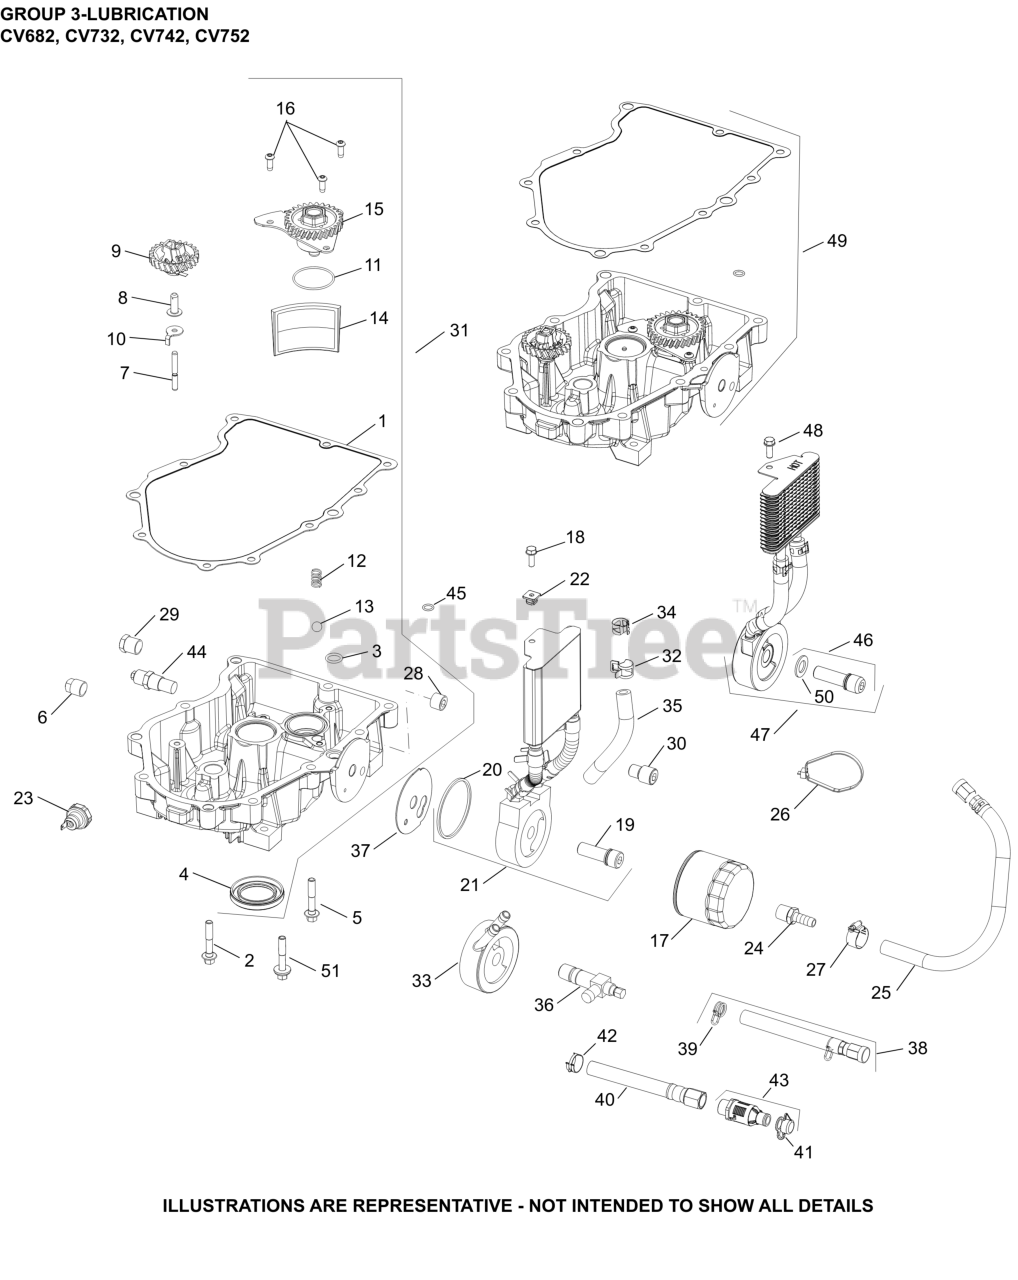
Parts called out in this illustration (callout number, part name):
1	KIT, OIL PAN GASKET
2	SCREW, FLG M8X1.25X45
5	SCREW, HEX FLANGE
8	PIN, GOVERNOR REGULATING
9	KIT, GOVERNOR GEAR W/PIN
10	TAB, LOCKING
11	O-RING (1.78" DIA)
12	SPRING, COMPRESSION
13	PRESSURE RELIEF BALL
14	SCREEN, OIL
15	PUMP, OIL ASSEMBLY
16	SCREW, BUTTON HEAD
17	OIL FILTER
20	O-RING, OIL COOLER
22	NUT, PLASTIC - BLACK
23	SENSOR, OIL PSI
28	PLUG, PIPE CTSK 3/8"
31	PAN, ASSEMBLY OIL (SERVICE)
34	CLAMP, HOSE LOW PROFILE
35	KIT, HOSE 140MM
45	O-RING (.5" DIA)
46	KIT, OIL FILTER NIPPLE
47	KIT, OIL COOLER
48	SCREW, HEX HEAD
50	WASHER, FLAT
NI	SHAFT, GOVERNOR GEAR
